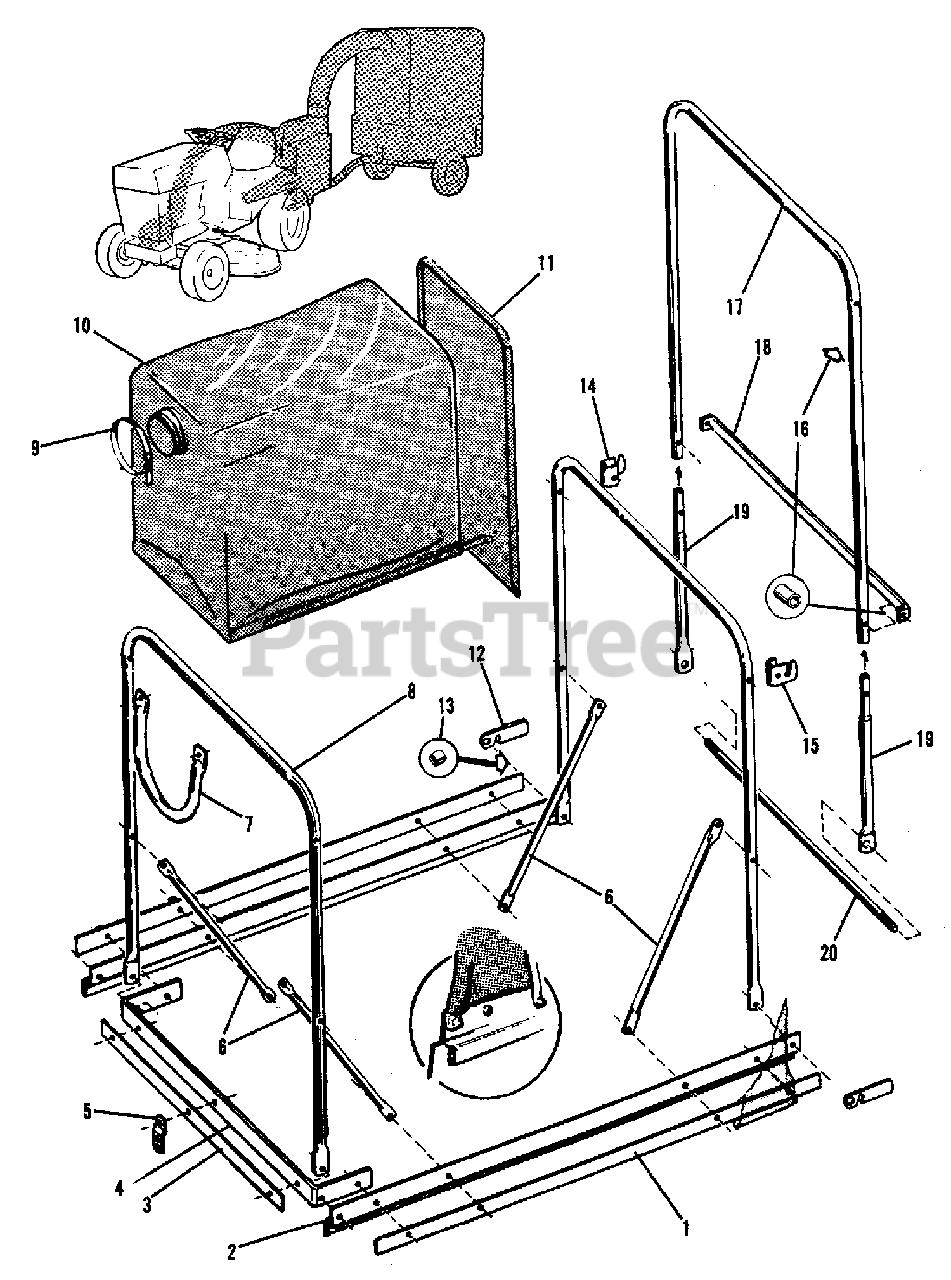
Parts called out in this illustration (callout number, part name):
1	STIP, Hold Down Side
1	CAPSCREW, 1/4NC x 3/4
1	NUT, 1/4NC
1	LOCKWASHER, 1/4
1	CAPSCREW, 5/16NC x 1
1	WASHER, 3/8 x 16 Ga.
1	LOCKWASHER, 5/16
1	NUT, 5/16NC
2	BAR, "2" Side
3	BAR, Front
4	STRIP, Hold Down, Front
4	CAPSCREW, 1/4NC x 3/4
4	WASHER, 5/16 x 3/4 x 16 Ga.
4	LOCKWASHER, 1/4
4	NUT, Lock, 3/8NC
5	CAPSCREW, 1/4NC x 1-1/4
5	LOCKWASHER, 1/4
5	NUT, 1/4NC
6	TUBE, Cross Brace
6	CAPSCREW, 1/4NC x 1-1/4 (Top)
6	LOCKWASHER, 1/4
6	NUT, 1/4NC
7	SUPPORT, Hose
7	CAPSCREW, 1/4NC x 1-1/4
7	LOCKWASHER, 1/4
7	NUT, 1/4NC
8	UPRIGHT, Front And Rear
9	STRAP, Hose
10	HOOD, Cart
11	COVER, Door
12	LATCH, Rear Door
12	CAPSCREW, 5/16NC x 7/8
12	WASHER, 3/8 x 7/8 x 16 Ga.
12	LOCKWASHER, 5/16
12	NUT, 5/16NC
13	SPACER, Latch
14	CATCH, Door R.H.
14	CAPSCREW, 1/4NC x 1-1/4
14	LOCKWASHER, 1/4
14	NUT, 1/4NC
15	CATCH, Door L.H.
15	CAPSCREW, 1/4NC x 1-1/4
15	LOCKWASHER, 1/4
15	NUT, 1/4NC
17	TOP, Rear Door
17	CAPSCREW, 1/4NC x 1-3/4 (Top Spacer)
17	WASHER, 5/16 x 3/4 x 16 Ga.
17	LOCKWASHER, 1/4
17	NUT, 1/4
18	BAR, Rear Door
18	CAPSCREW, 1/4NC x 1-1/2
18	WASHER, 5/16 x 3/4 x 16 Ga.
18	LOCKWASHER, 1/4
18	NUT, 1/4
19	TUBE, Rear Door
20	ROD, Rear Door
20	NUT, 1/2NC
20	LOCKWASHER, 1/2
